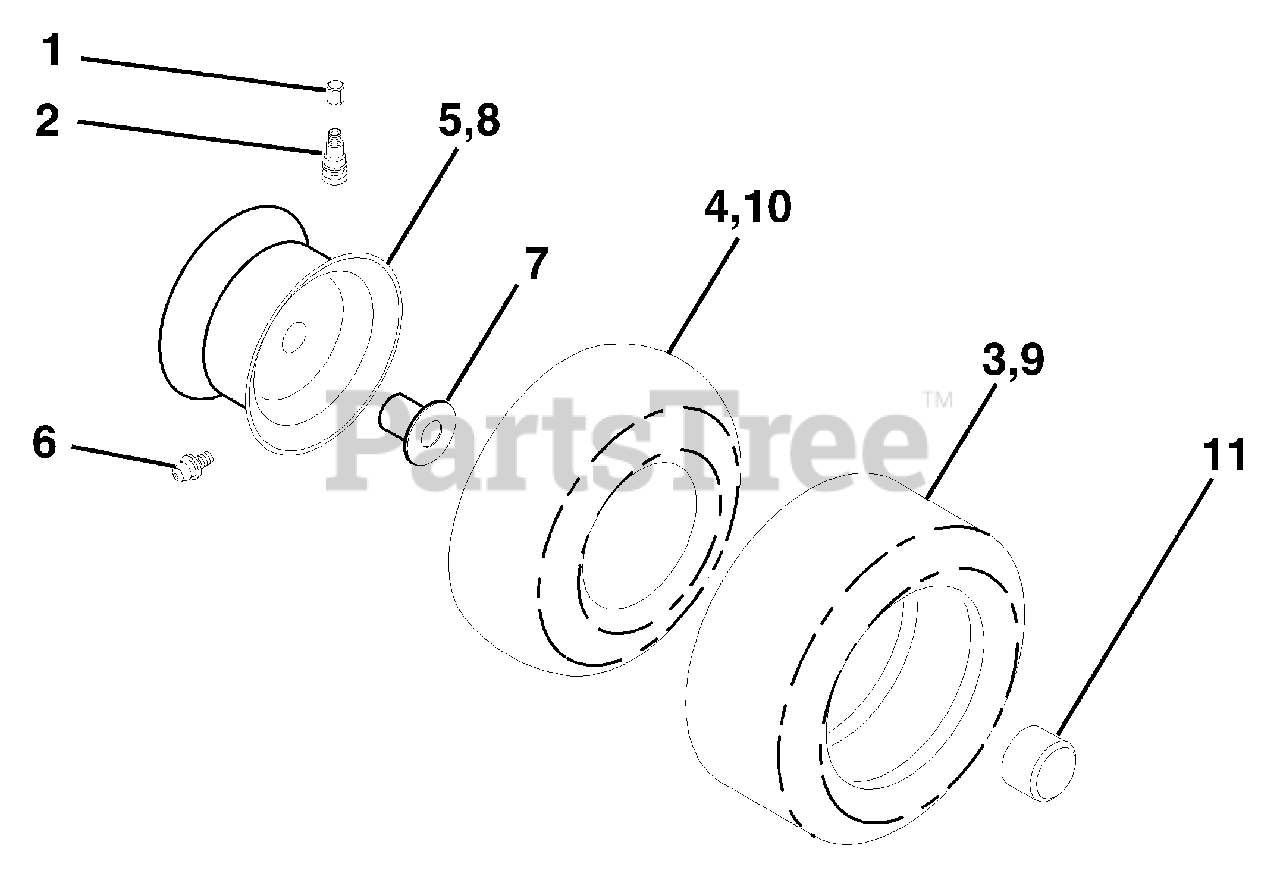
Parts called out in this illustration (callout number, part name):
1	Cap Value Tire
2	Stem Value
3	Tire F Ts 15 X 6 0 - 6 Service
4	Tube Inner Front #35060
5	Rim Asm 6"front White Service
6	Fitting Grease
7	Bearing Flange
8	Rim Asm 8"rear White Service
9	Tire R Ts 18 x 8.5-8 Service
10	Tube Rear 9 5 X 8 Service
11	Cap Axle Blk 1 50 X 1 00
